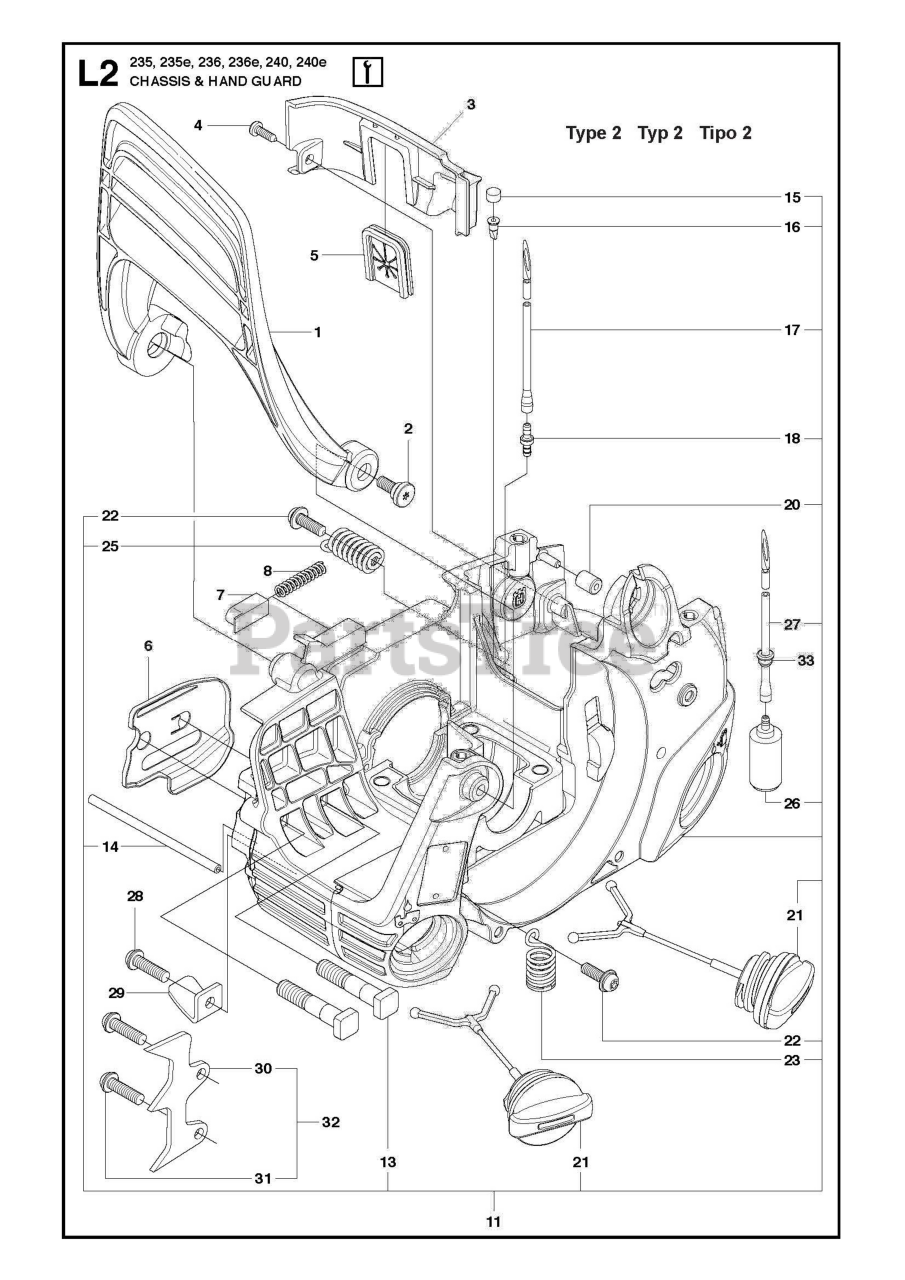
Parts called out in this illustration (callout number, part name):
1	HANDGUARD HHS
2	BOSS SCREW
4	SCREW 6-19X.437
7	CAP, SPRING HANDGUARD
11	CHASSIS ASSEMBLY, P021, MACH.
13	BOLT
15	VENT,FUEL TANK 36/41
16	VALVE-CHECK (DUCKBILL)
17	FUEL LINE
18	FUEL LINE FITTING
20	ISOLATOR FILTER HOUSING
21	TANK CAP ASSY
22	SCREW,FRONT HBAR 36/41
26	ASSY FUEL PICKUP PRE FLUSHED
27	LINE FUEL LOW PERM
29	CHAIN CATCHER 36/41
30	SPIKE
32	SPIKE 36/41
33	FUEL TANK BUSHING
